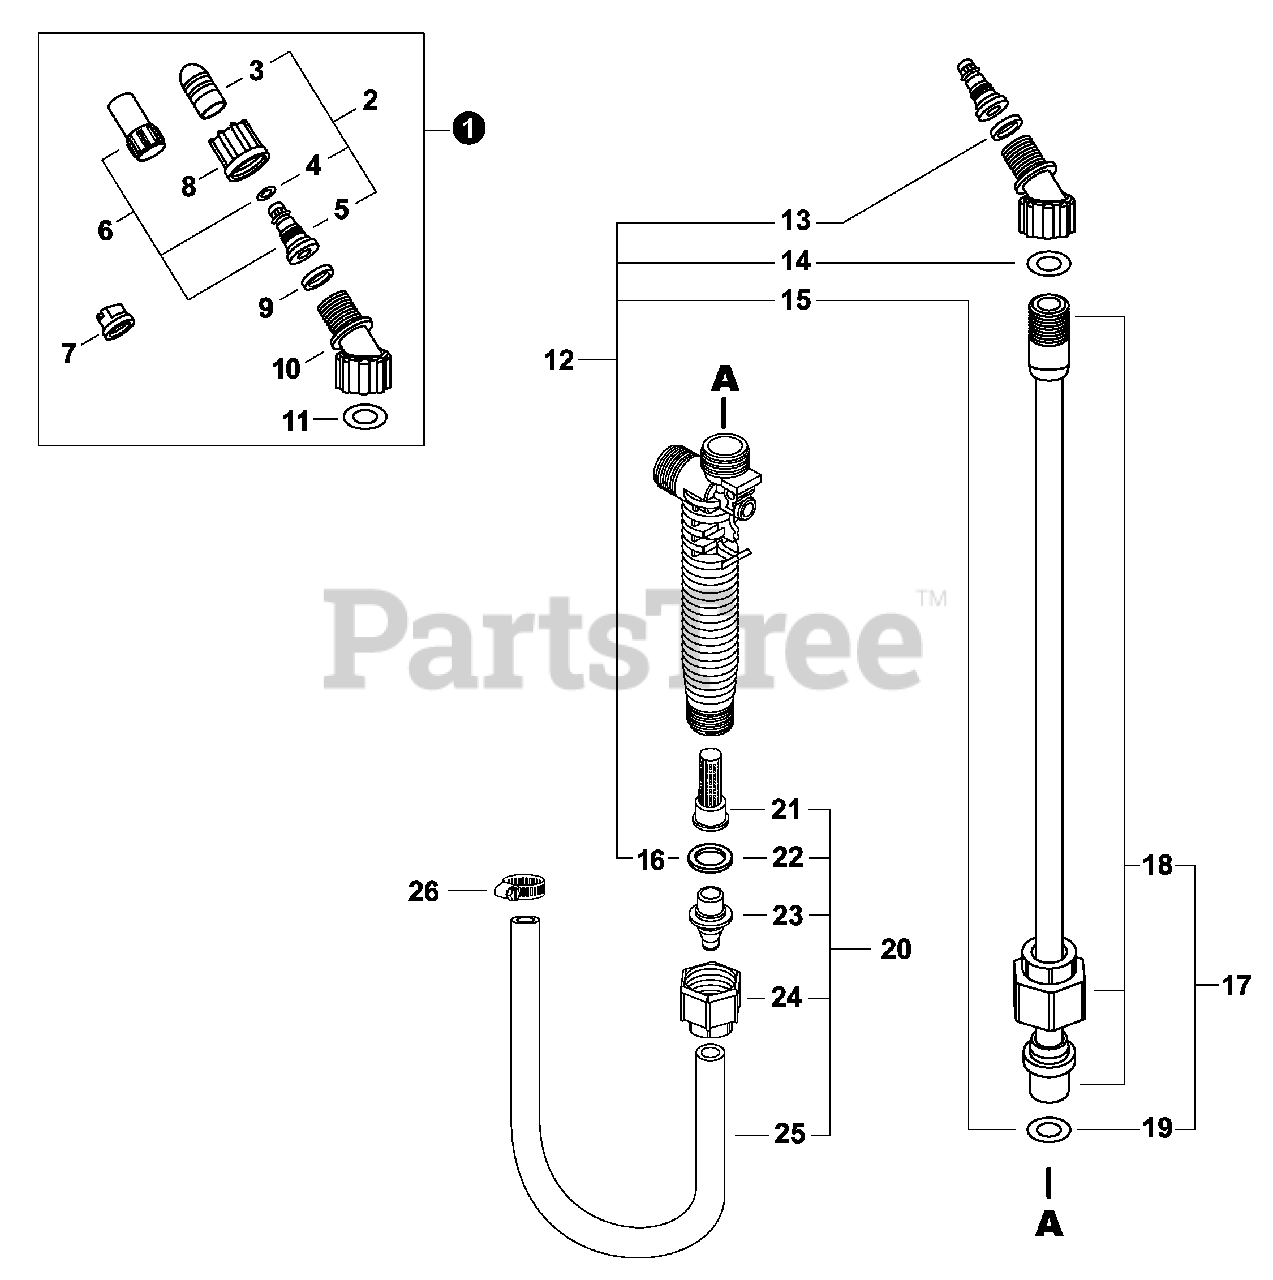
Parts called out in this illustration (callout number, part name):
1	NOZZLE KIT
2	NOZZLE KIT, BRASS
3	CAP, NOZZLE - BRASS
4	O-RING, NOZZLE
5	BODY, NOZZLE
6	NOZZLE KIT, PLASTIC
7	NOZZLE, FLAT FAN
8	NUT, NOZZLE
9	GASKET, NOZZLE
10	ELBOW, NOZZLE
11	O-RING, ELBOW
12	GASKET KIT, WAND
13	GASKET, NOZZLE
14	O-RING, ELBOW
16	GASKET, ADAPTER
17	WAND ASSY, METAL
18	WAND, METAL
20	HOSE KIT
21	FILTER, SPRAY GUN
22	GASKET, ADAPTER
23	ADAPTER, HOSE - BLACK
24	NUT, HOSE
26	CLAMP, HOSE
